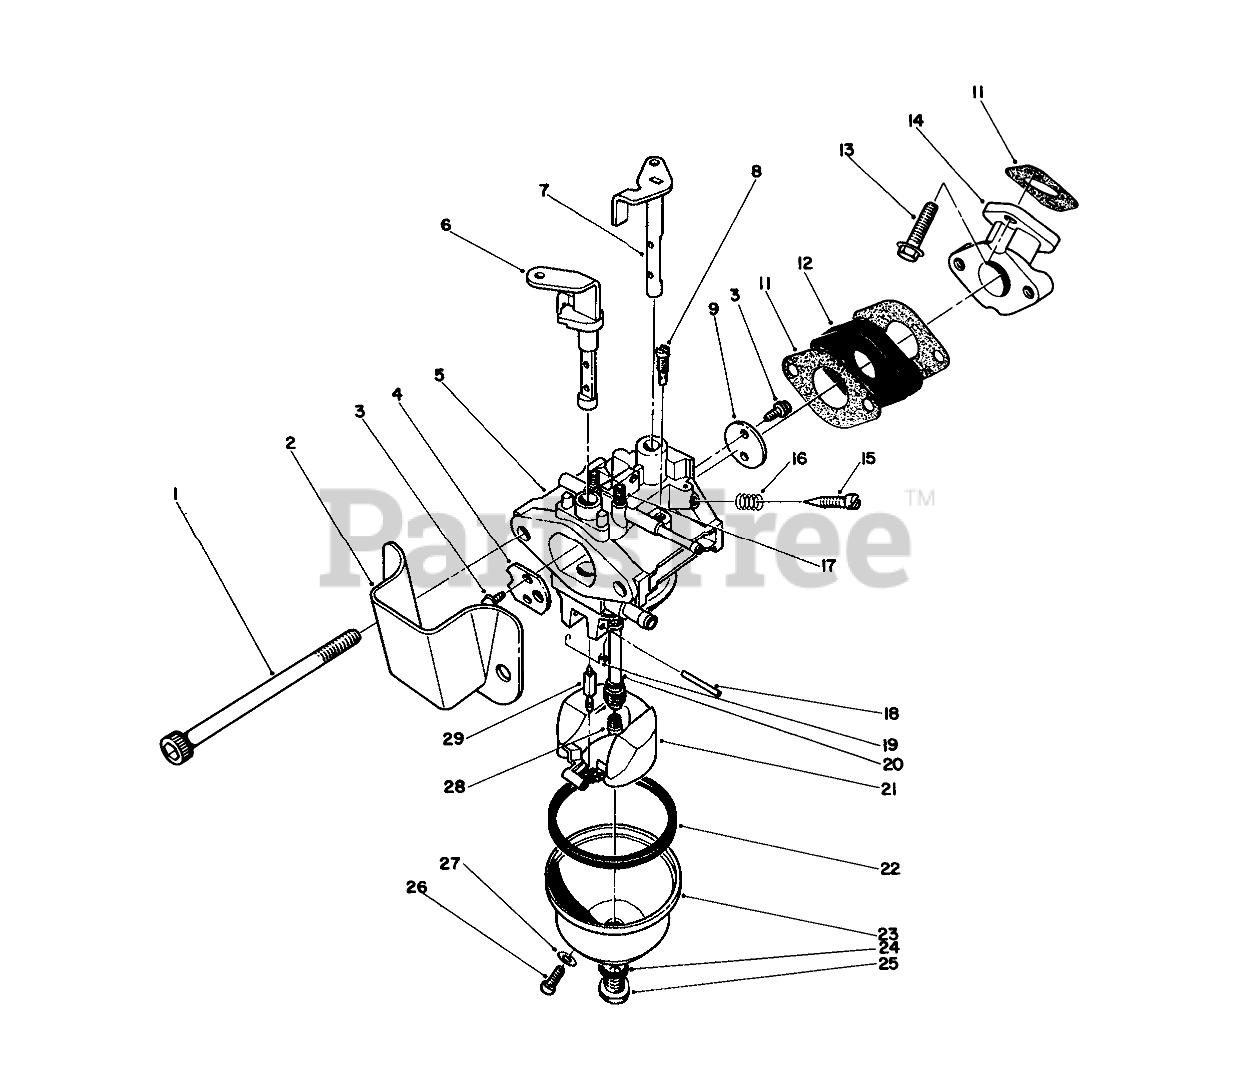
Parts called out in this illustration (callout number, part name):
2	SPIT CUP
3	Screw
4	VALVE
5	Body-Carburetor
6	SHAFT
7	SHAFT
9	VALVE
11	Gasket-Carburetor
12	CARB INSULATOR
14	MANIFOLD
15	ADJUSTER
16	SPRING-PILOT SCREW
17	SPRING
18	PIN-HINGE
19	TORSION SPRING
20	MAIN NOZZLE
21	Float
22	FLOAT BOWL GASKET
24	GASKET
25	SCREW
26	SCREW
27	GASKET
28	MAIN JET
29	NEEDLE
